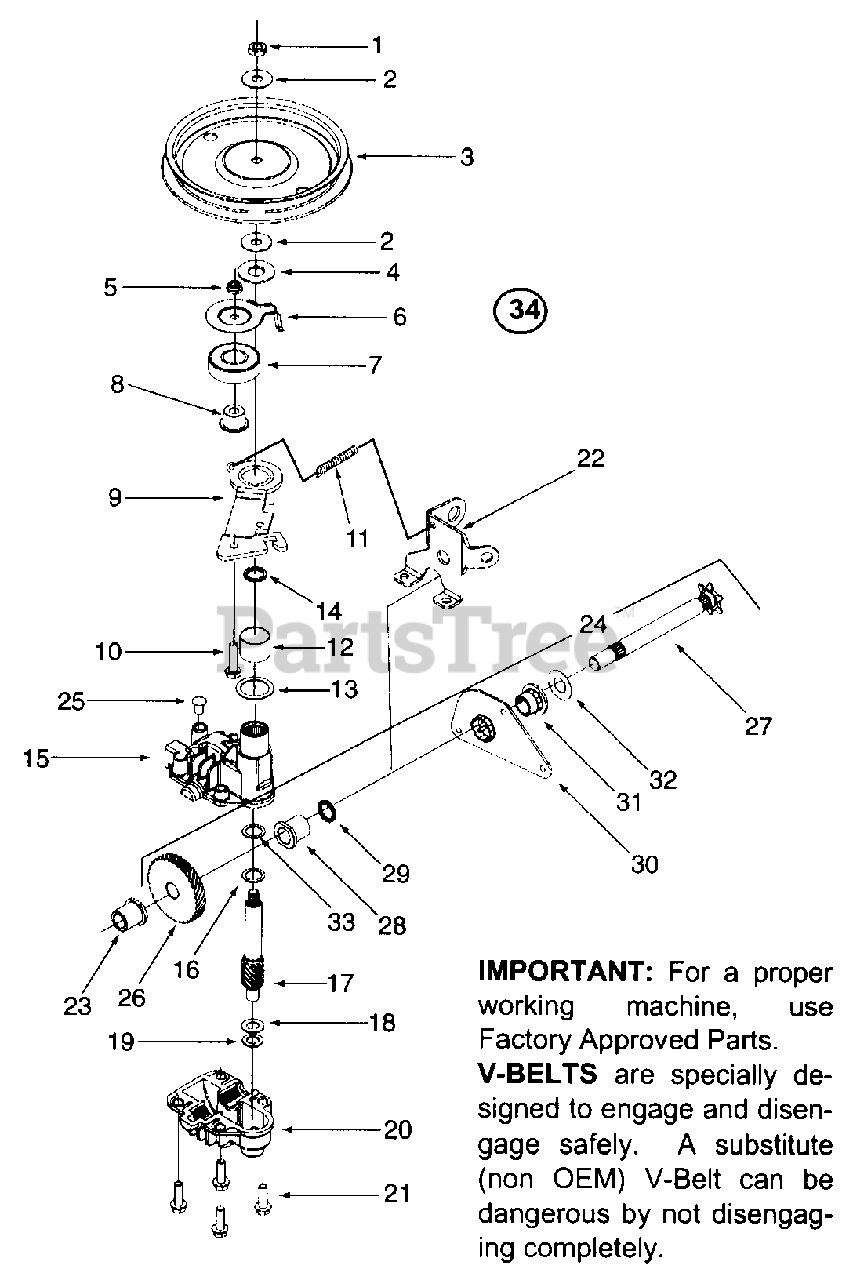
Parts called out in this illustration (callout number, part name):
1	Hex Jam Nut 5/16-24
2	Bell Washer .325 x .930
4	Flat Washer .510 x 1.120
5	Hex Jam Nut 1/4-28
7	Bearing
8	Flange Spacer
9	Idler Bracket Assembly
10	Hex Cap Screw 1/4-28 x 1.0
11	Extension Spring
12	Bearing Sleeve
13	Flat Washer .885 x 1.45
14	Oil Seal
15	Upper Housing Assembly
16	Thrust Washer .504 x .70
17	Pinion Shaft 10T
18	Thrust Washer 3/8 x .70
19	Thrust Washer .388 x .625
20	Lower Housing Assembly
21	Hex Screw 1/2-20 x .75
24	Shaft Assembly
27	Output Shaft 6T
28	Flange Bearing
29	Oil Seal
30	Pivot Bracket
31	Flange Bearing
32	Flat Washer .508 ID x 1.0
34	Transmission Assy.
